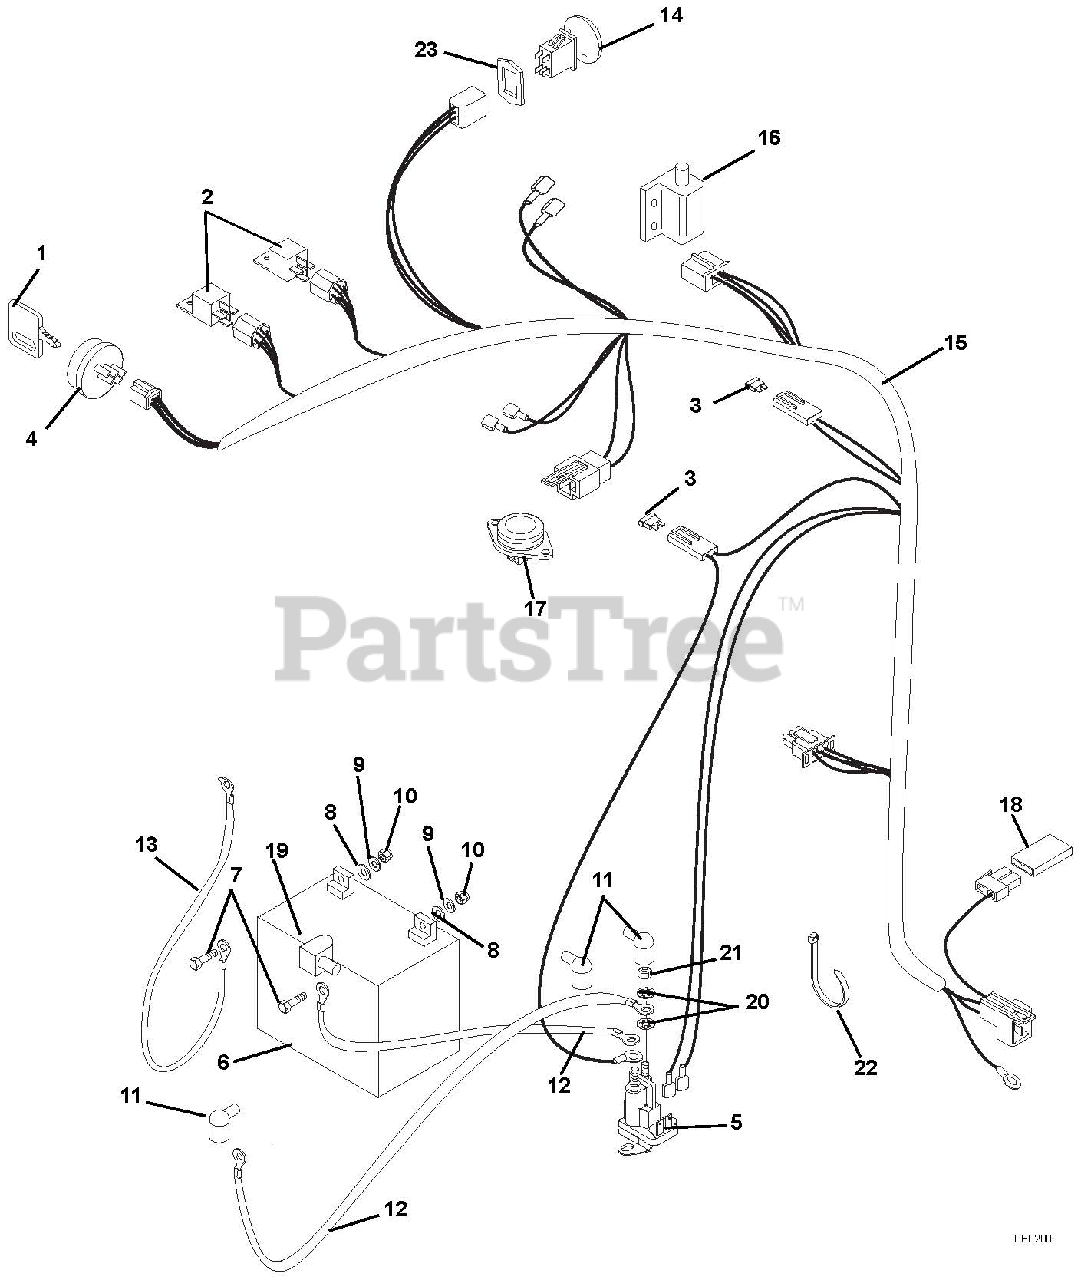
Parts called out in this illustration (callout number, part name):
1	KEY -W/CAP
2	RELAY
3	FUSE-25 AMP ATC TYPE
4	KEY SWITCH
5	SOLENOID
6	BATTERY, 300 CCA 10U1L
7	@BLT-HEX .25-20X.75 GR5 YWZC
8	@WSHR-FL-STL.281X.62X.065 YWZC
9	@WSHR-LK .25X.062 REG YWZC
10	@NUT-HEX .25-20 YWZC
11	BOOT, EYELET TERMINAL
12	STARTER CABLE 13"
13	GROUND CABLE .31X22.00X.31
14	SWITCH, CLUTCH
15	WIRE HARNESS
16	SWITCH- DOUBLE POLE N.O./N.O.
17	SWITCH- SNAP MTG N.O.
18	DIODE, CONNECTOR SHELL
19	INSULATOR
20	WSHR-LOCK INT .31 YWZC
21	NUT-JAM .31-24 YWZC
22	CABLE TIE LG 5-1/2
23	SHIM,PTO SW (DELTA #972301)
